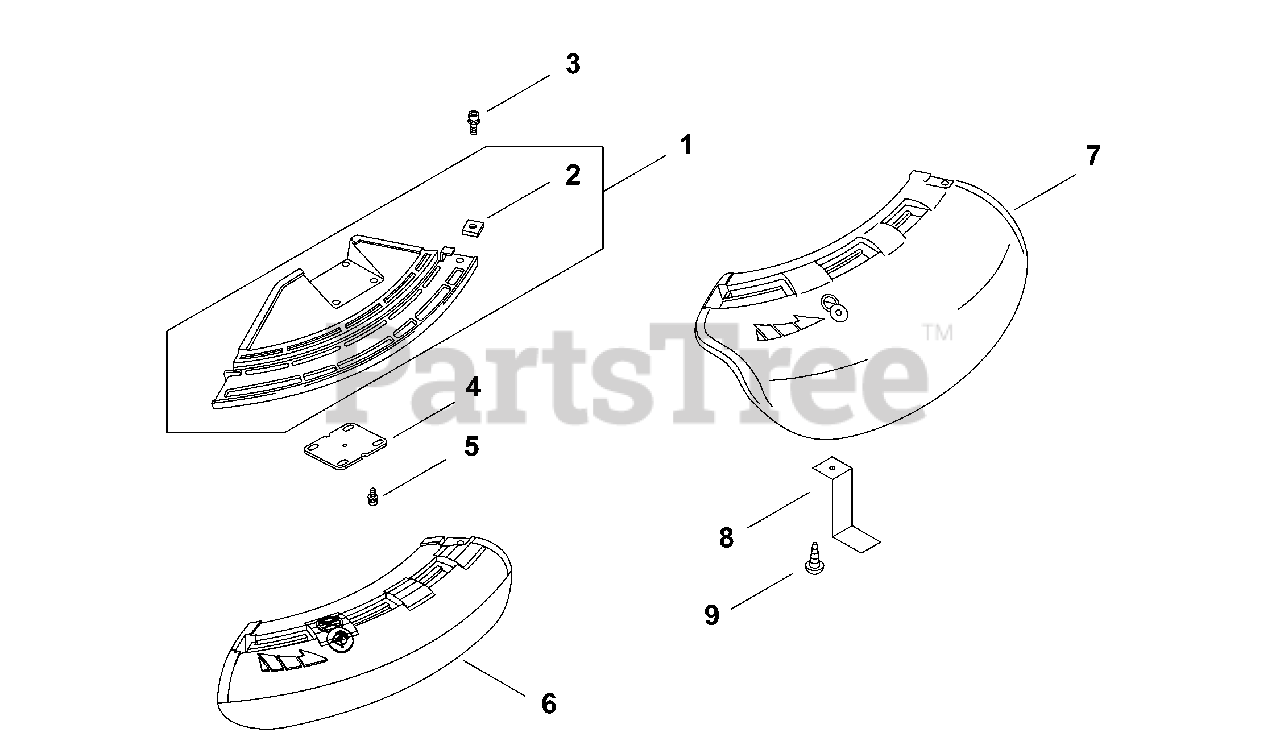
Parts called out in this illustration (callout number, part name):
1	DEBRIS SHIELD BASE ASSY
2	NUT M5
3	BOLT 5×22
4	PLATE, SHIELD
5	BOLT 5×25
6	SHIELD, DEBRIS - BLADE EXTENSION
7	SHIELD, DEBRIS - TRIMMER EXTENSION
8	CUTTER, LINE
9	SCREW, TAPPING 5×12
